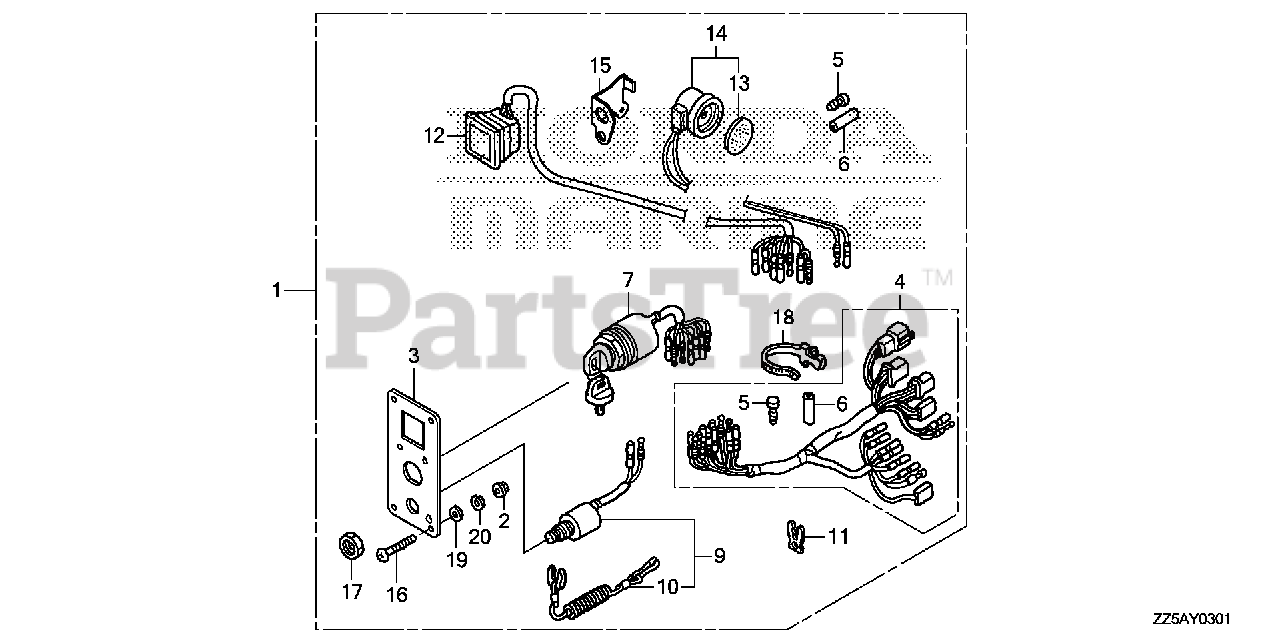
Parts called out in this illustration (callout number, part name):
1	PANEL KIT, SWITCH (4-LED)
2	NUT, FLANGE (5MM)
3	PANEL, CONTROL
4	HARNESS ASSY., SWITCH PANEL
5	PLUG, CONNECTOR (INNER)
6	PLUG, CONNECTOR (OUTER)
7	SWITCH ASSY., COMBINATION
9	SWITCH ASSY., EMERGENCY STOP
10	WIRE, EMERGENCY
11	CLIP, EMERGENCY LOCK
12	LAMP ASSY., INDICATION (4-LED)
13	PLATE, TURN SIGNAL BUZZER
14	BUZZER, WARNING
15	BRACKET, BUZZER
16	SCREW, PAN (5X40)
17	NUT, HEX. (16MM)
18	BAND, WIRE HARNESS (150MM) (NATURAL)
19	WASHER, PLAIN (5MM)
20	WASHER, SPRING (5MM)
